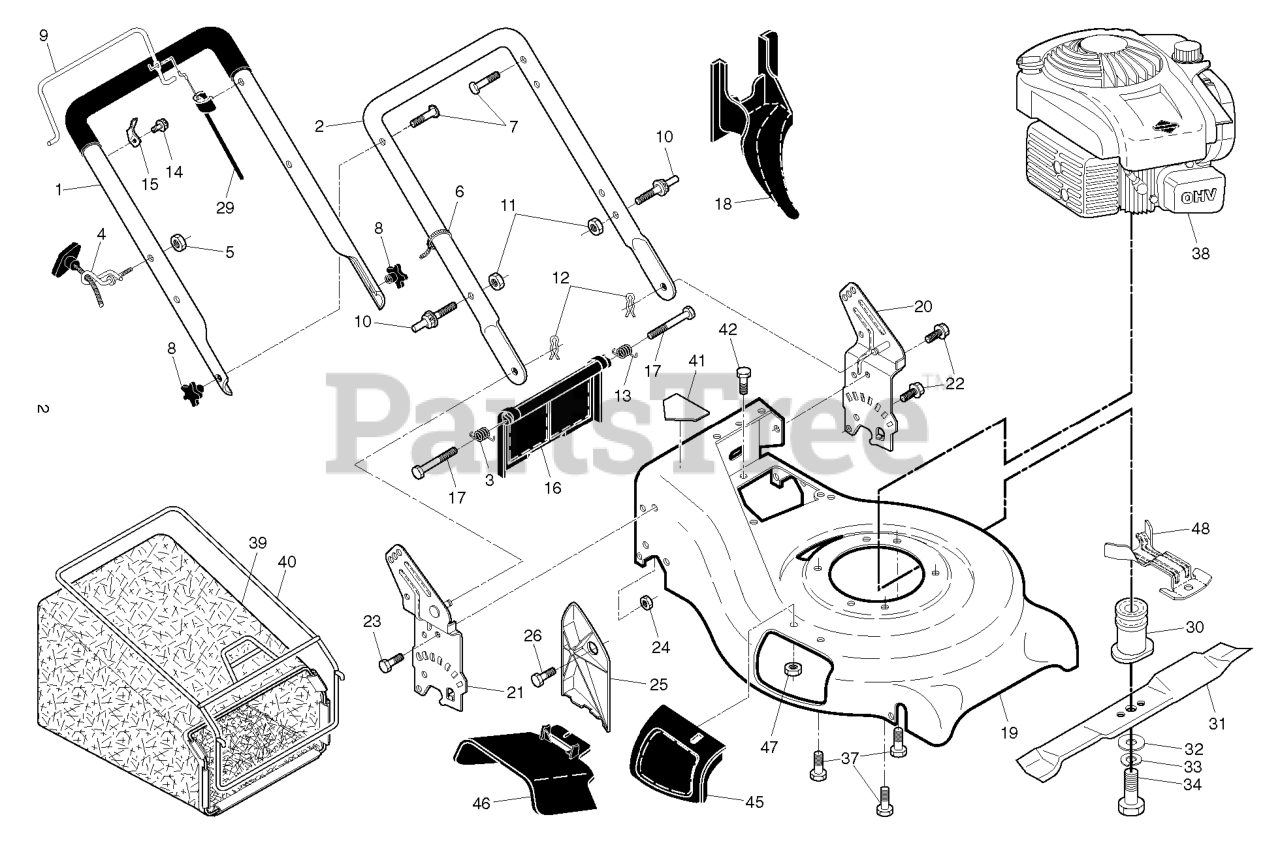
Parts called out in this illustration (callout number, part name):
1	LARGE AUTOMOWER INSTALL KIT
1	MED AUTOMOWER INSTALL KIT
1	SMALL AUTOMOWER INSTALL KIT
2	CONNECTOR 5 PCS, BLISTER
2	BRAKER
3	COUPLER SPLICER, 100 PCS
3	COUPLER SPLICER, 5 PCS,
3	SPLICE KIT
4	STAPLE 100 PCS
5	HUS BLADE SET 45 PCS
5	HUS BLADE SET 9 PCS
5	HUS BLADE SET 300 PCS
6	WIRE 50M STANDARD Ø2.7MM,BLIST
6	WIRE BOUNDARY 150M
6	WIRE 150M, BLISTER
7	WIRE 250M
8	WIRE 500M
9	WIRE (800M)
10	POWER UNIT POWER SUPPLY 1,3A
11	POWER UNIT US
12	RULER / CENTIMETERS
13	CABLE ASSY LOW VOLTAGE CABLE
14	CABLE ASSY LOW VOLTAGE CABLE
15	CABLE ASSY LOW VOLTAGE CABLE
18	SCREW KIT ANCHOR SCREW 5 PCS
19	STICKER CABLE MARKERS KIT 10PC
20	LABEL SECURITY
